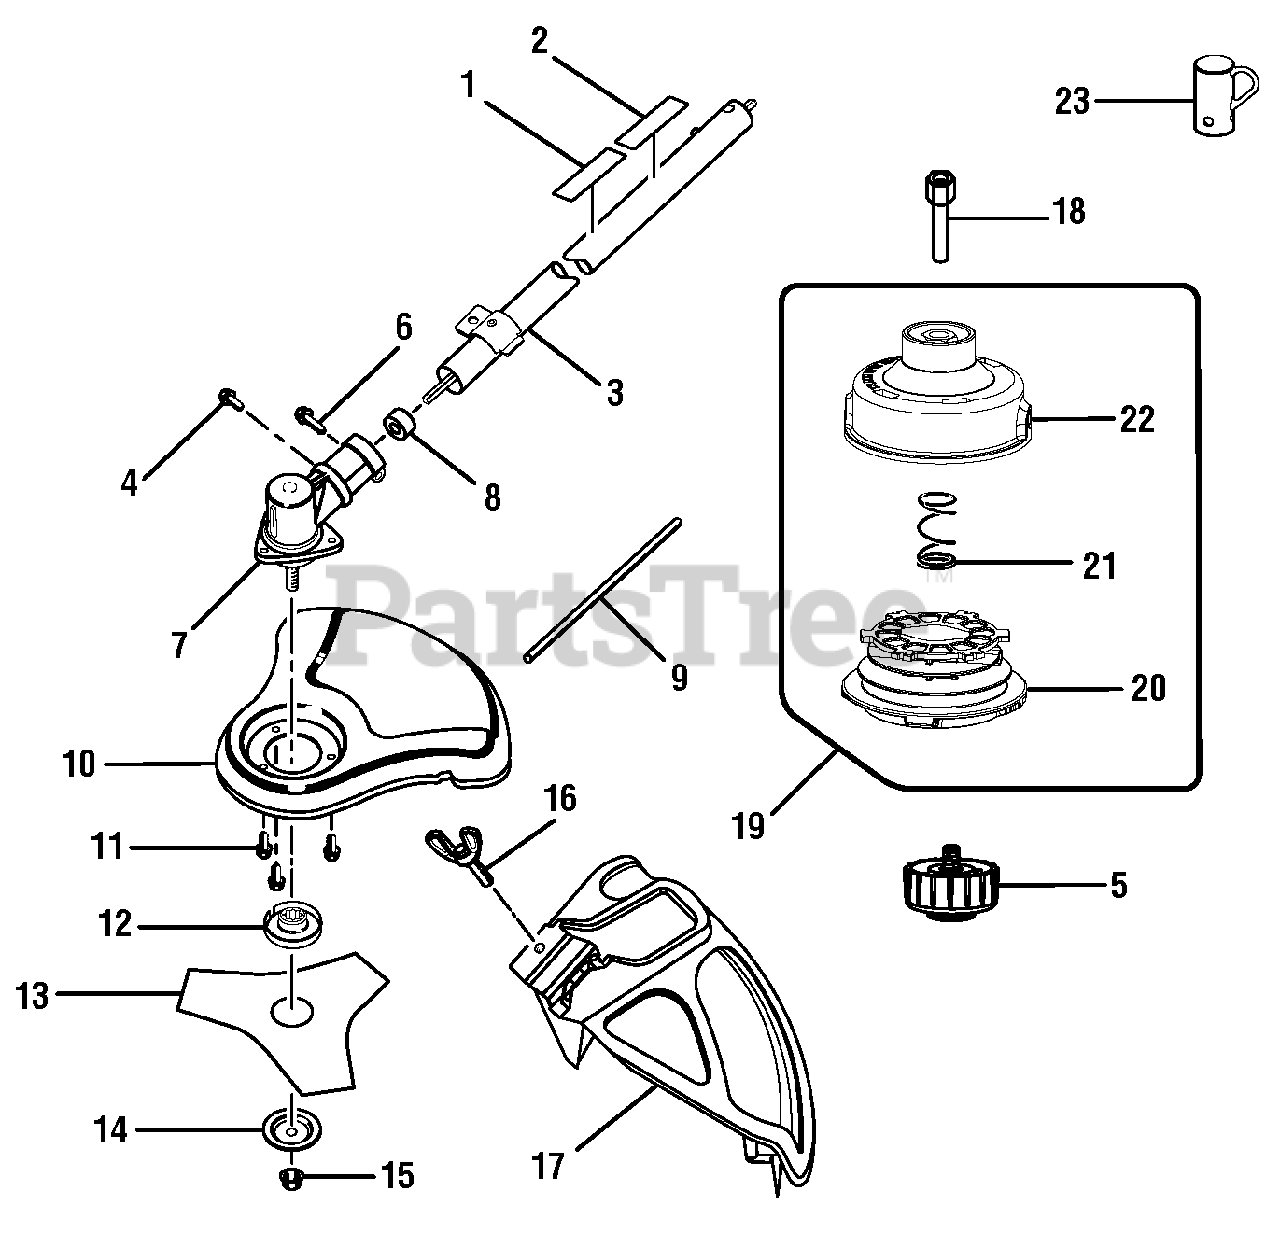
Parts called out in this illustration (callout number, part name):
1	Expand-it Label
2	Brushcutter Safety Label
3	Lower Straight Shaft Boom Assembly
4	Screw (10-24 x 5/8 in.)
5	Spool Retainer
6	Screw (1/4-20 x 1-1/4 in.)
7	Gear Head
9	Gear Head Locking Tool
10	Brushcutter Guard
11	Screw (10-24 x 1/2 in.)
12	Flanged Washer
14	Cupped Washer
15	Blade Nut
16	Screw (1/4-20 x 1-1/4 in.)
17	Grass Deflector Assembly
19	String Head Assembly
20	Spool Assembly
22	String Head Housing
23	Hanger Cap
